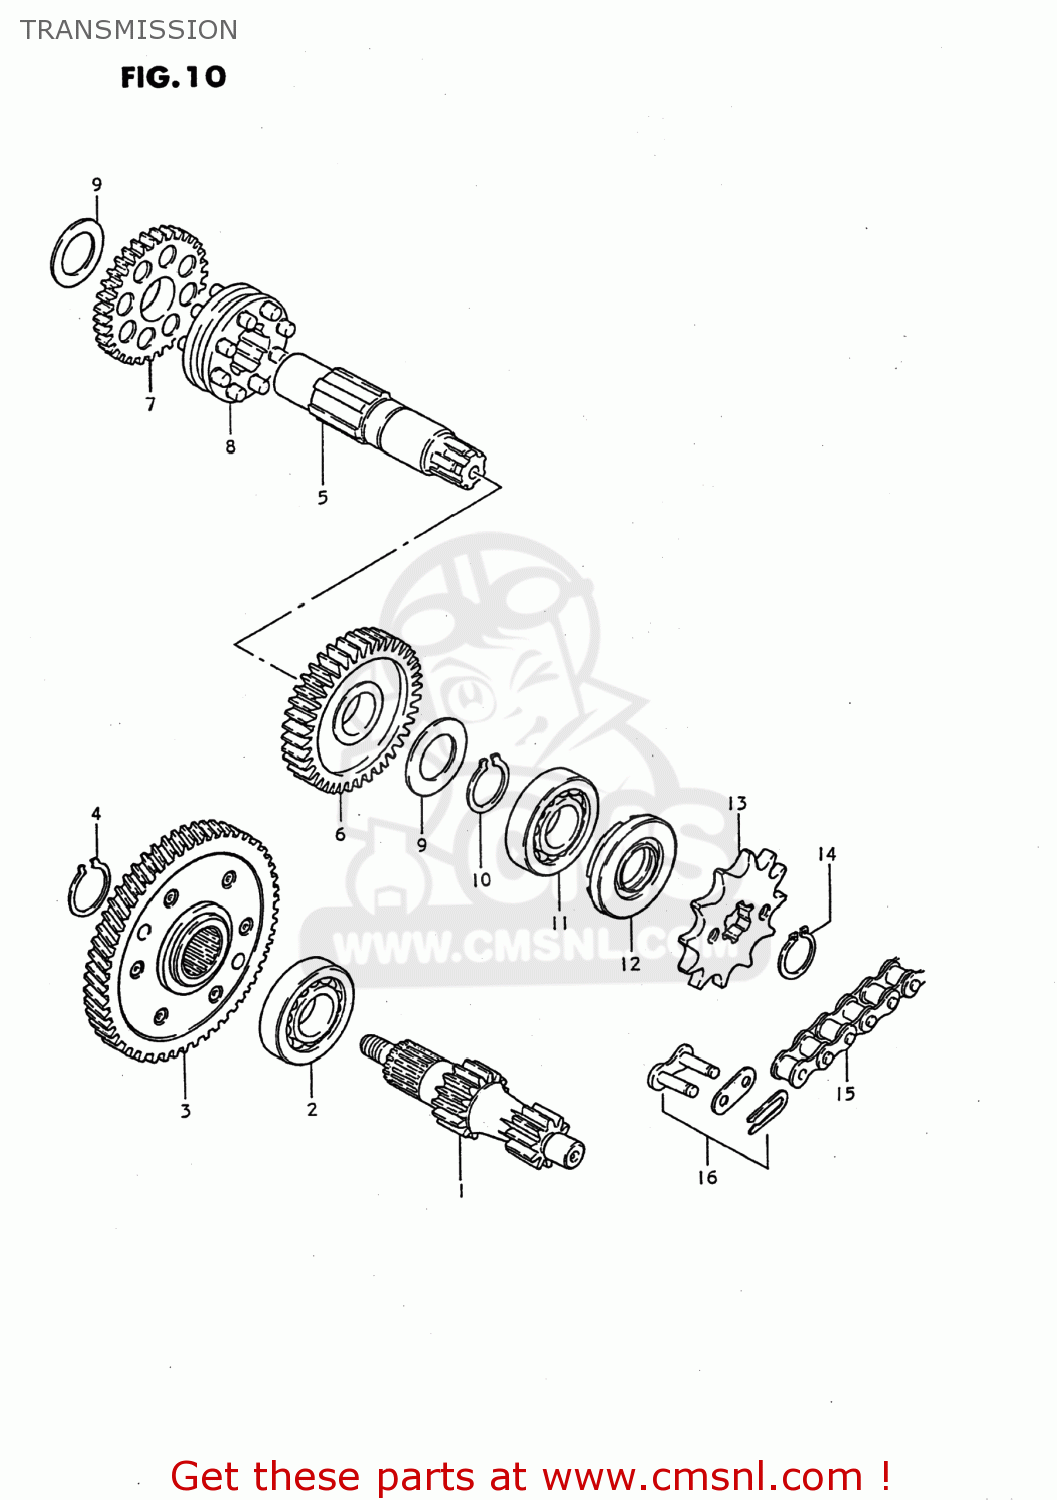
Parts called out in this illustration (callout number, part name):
1	SHAFT,COUNTER
2	BEARING(17X40X12)
3	GEAR ASSY,PRI DRIVEN
4	CIRCLIP
5	SHAFT,DRIVE
6	GEAR,FIRST DRIVEN
7	GEAR,SECOND DRIVEN
8	WHEEL,1ST GEAR
9	WASHER,THRUST
10	CIRCLIP
11	BEARING(17X40X12)
12	SEAL,OIL(17X29X7)
13	SPROCKET,ENGINE
14	CIRCLIP 16MM
15	CHAIN ASSEMBLY,DRIVE
16	JOINT
